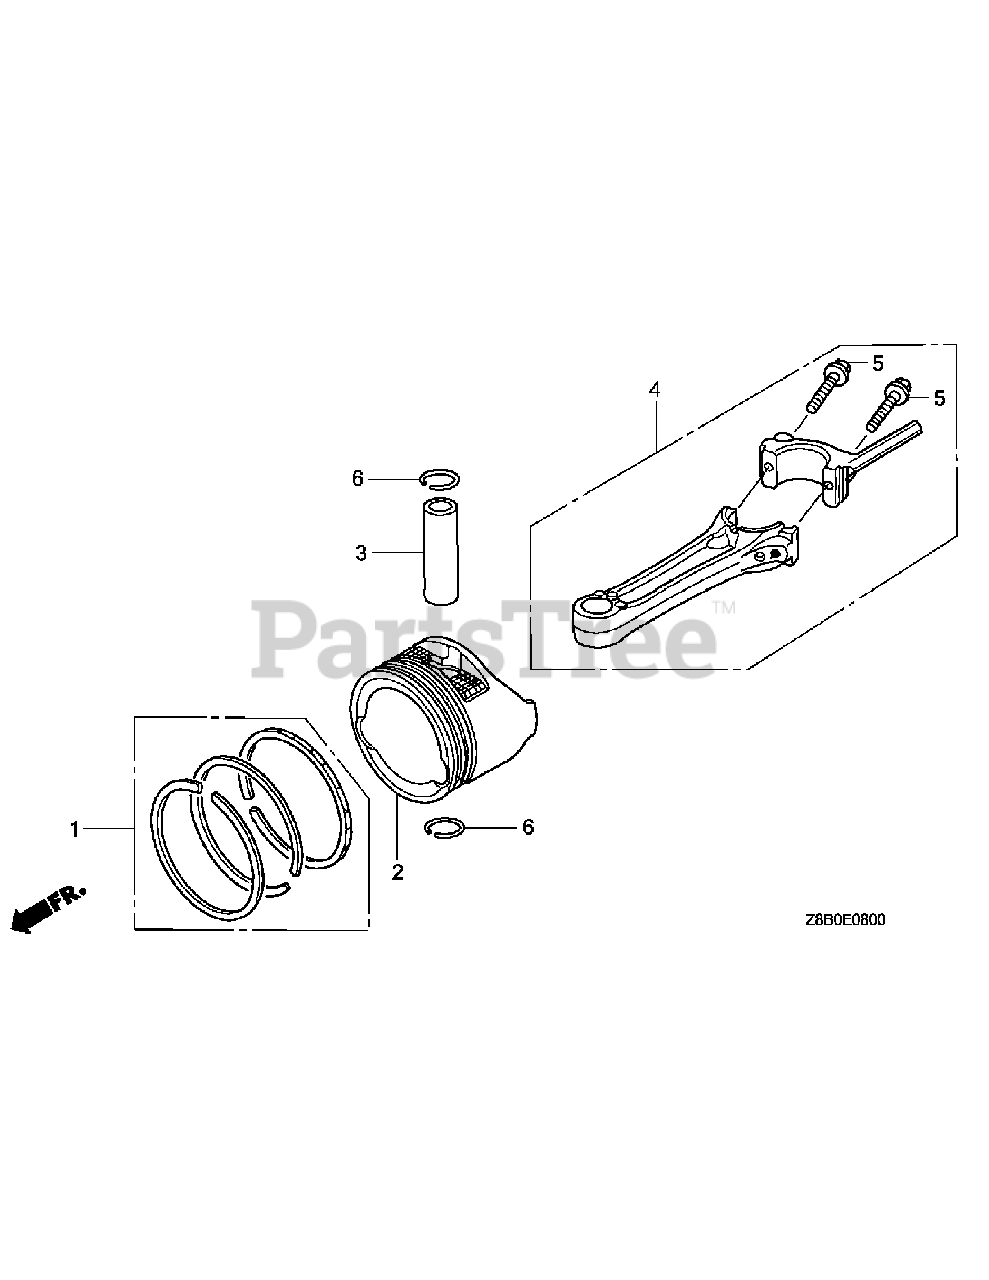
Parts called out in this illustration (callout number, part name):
1	RING SET, PISTON (STD) (Honda Code 8571937). (TEIKOKU)
2	PISTON
3	PIN, PISTON
4	ROD ASSY., CONNECTING
5	BOLT, CONNECTING ROD
6	CLIP, PISTON PIN (13MM)
